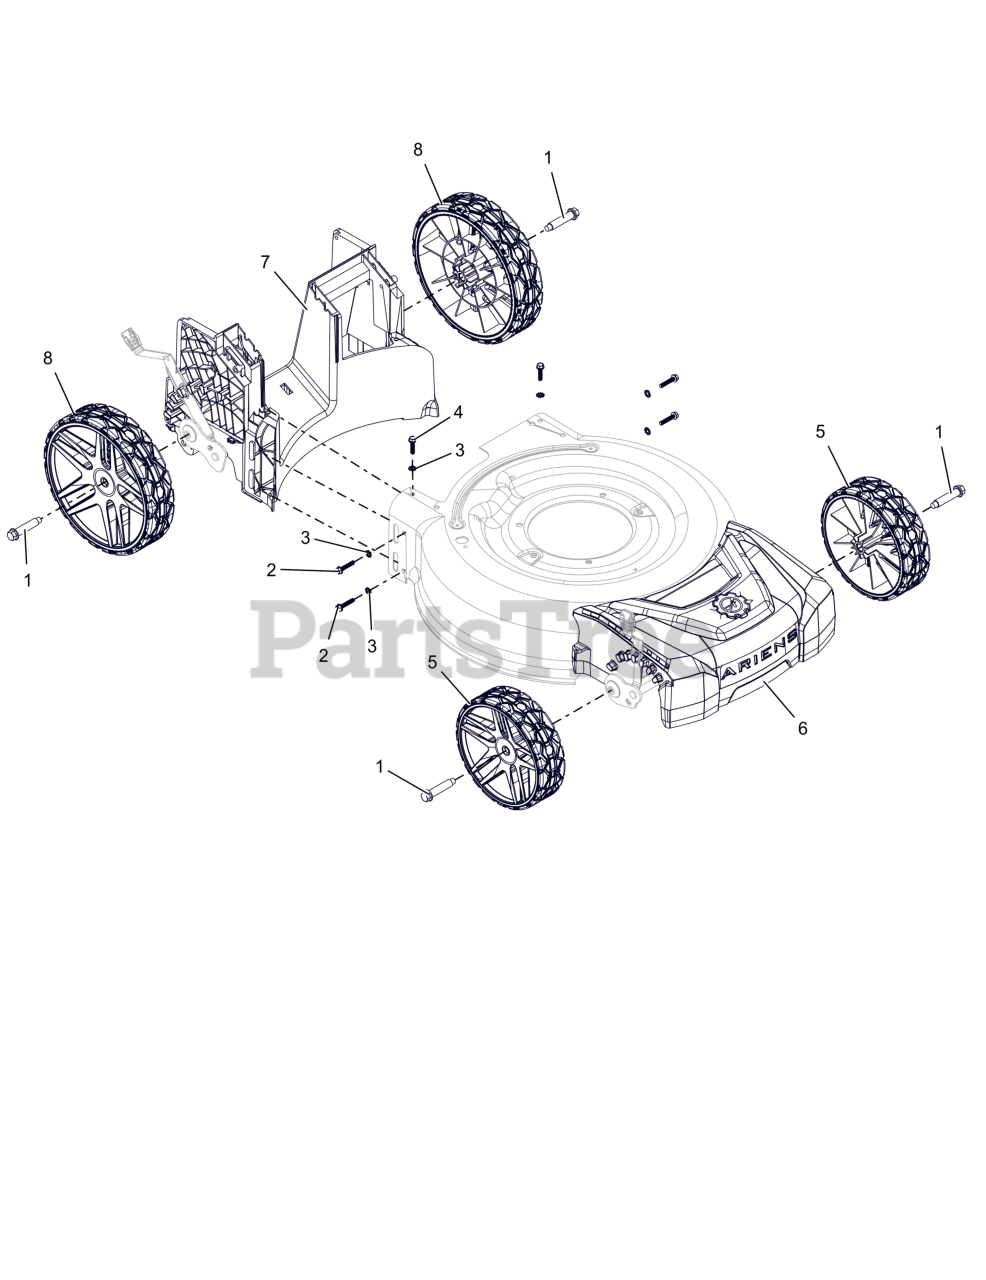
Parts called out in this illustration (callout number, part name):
1	BLT, SHLDR HWH .325X1.981X 3/8-16
2	SCR, HI-LO HWH 1/4-15 X 1.25
3	WSHR-LK-EXT, .256X.510X.028
4	SCR, HI-LO HWH 1/4-15 X 1.00
5	WHEEL, 8" - GRAY
6	COVER, FRONT
7	BAFFLE, FWD
8	WHEEL, 10" - GRAY
